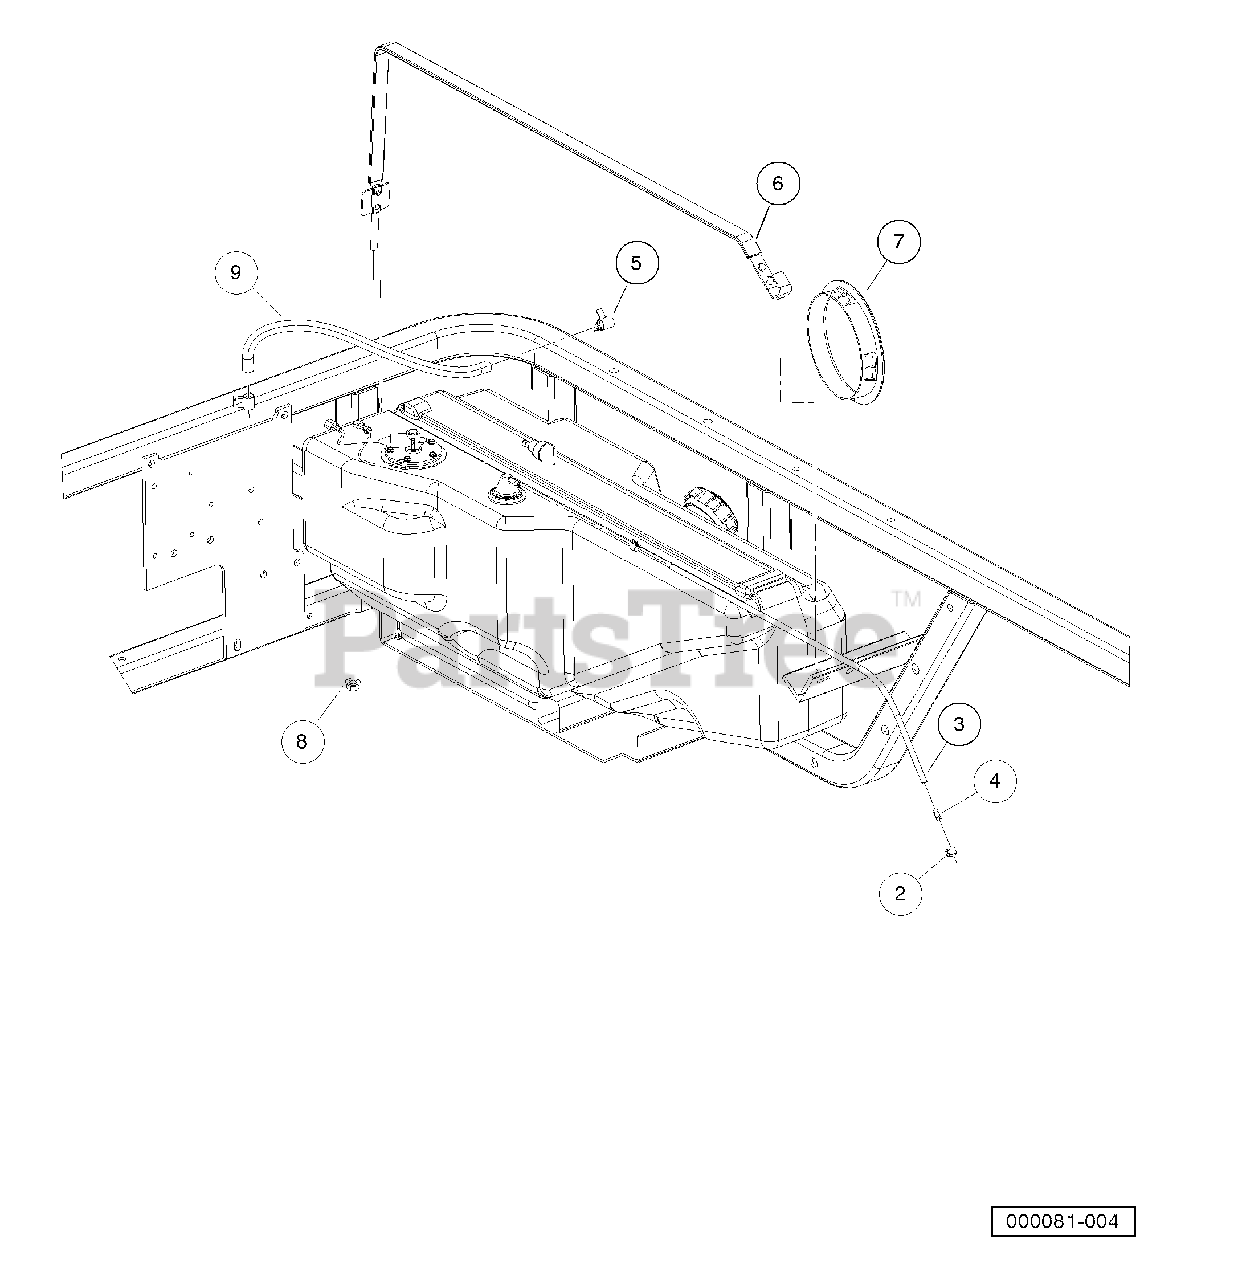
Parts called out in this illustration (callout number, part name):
1	Instl, Fuel System, Honda
2	Clamp, 0.301 ID Hose
3	Hose, Fuel, Vent
5	Clamp, Hose, Ctb 13mm
6	Strap, Tank, Fuel
7	Bezel, Fuel Fill
8	Lock Nut, Flg M8 X 1.25 Nylon
9	Hose, Tank To Filter, Fh680d
